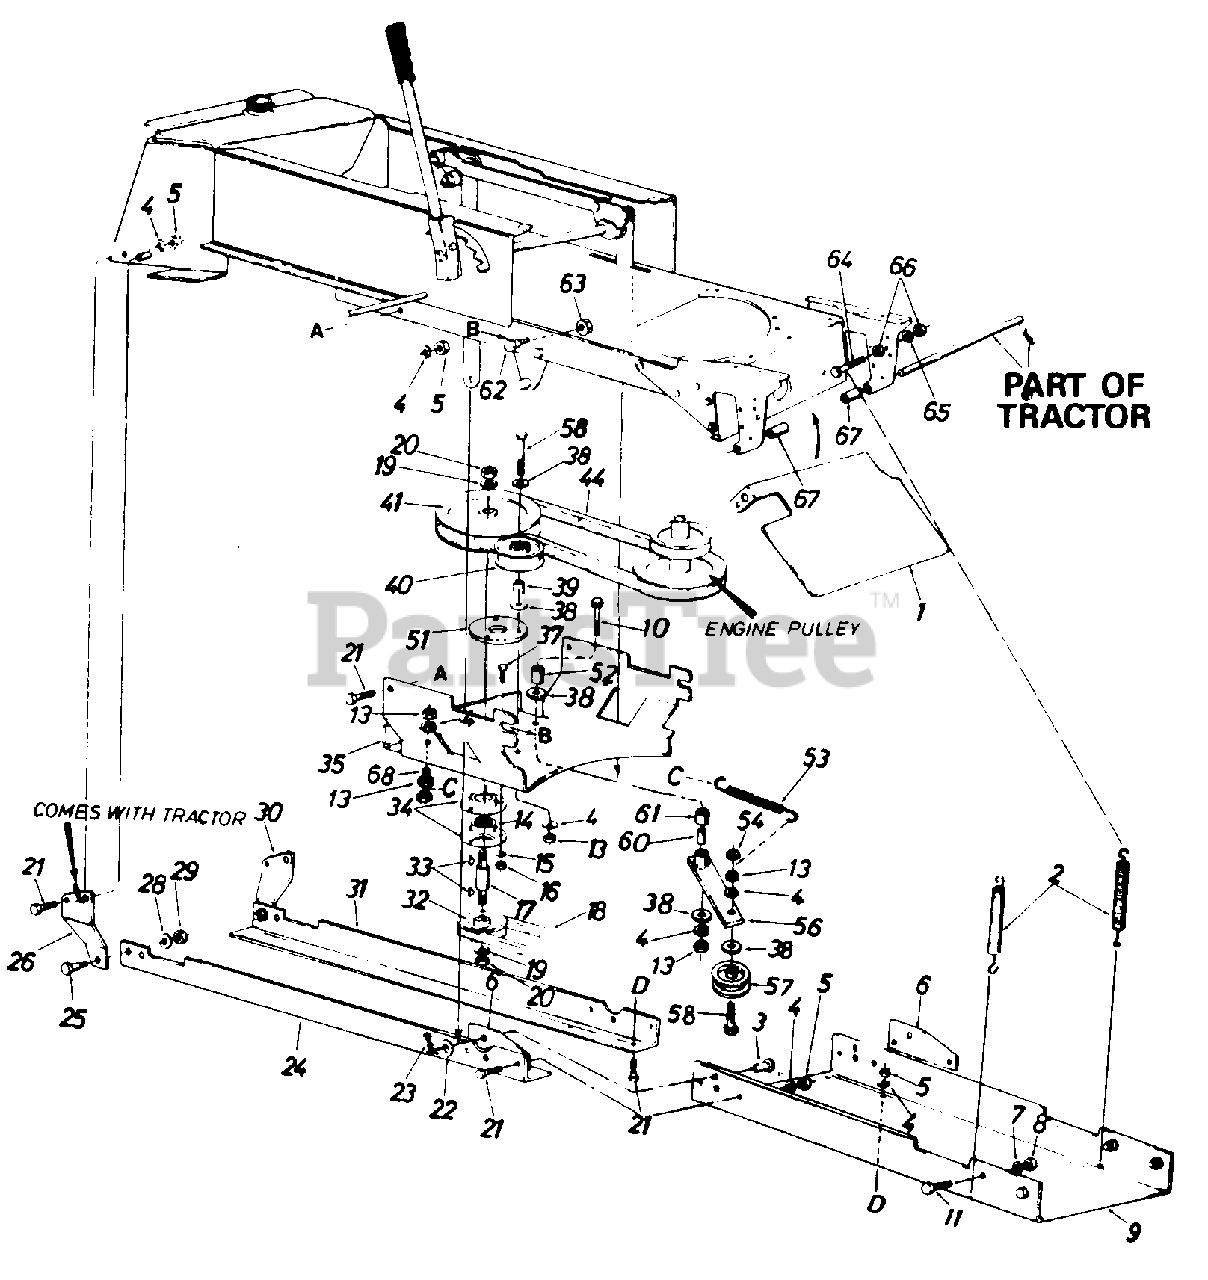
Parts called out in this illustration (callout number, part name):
3	Clevis Pin
4	L.-Wash. 3/8" I.D.
5	Hex L.-Nut 3/8-24 Thd.
6	Attaching Plate
7	L.-Wash. 1/2" I.D.
8	Hex L.-Nut 1/2-20 Thd.
11	Hex Bolt 1/2-20 x 1.25" Lg.
13	Hex Jam Nut 3/8-16 Thd.
14	Ball Beariny
15	L.-Wash. 5/16" I.D.
16	Hex Nut 5/16-18 Thd.
17	Spindle
18	"V"-Belt
19	L.-Wash. 5/8" I.D.
20	Hex Jam Nut 5/8-11 Thd.
21	Hex Bolt 3/8-24 x 1.00" Lg.
22	Flat Washer
23	Internal Cotter Pin
29	Hex Nut 7/16-14 Thd.
33	#6 Hi-Pro Key 3/16 x 5/8" Dia.
34	Bearing Housing
35	Supporting Bracket
37	Hex Sems Bolt 5/16-18 x 1"
38	Fl.-Wash. .38" I.D. x 1" O.D.
39	Spacer .38" I.D. x .62' O.D.
40	Fl.-Idler Pulley
41	Upper Drive Pulley
44	"V"-Belt
53	Extension Spring 4.75" Lg.
54	Hex Cent. L.-Nut 3/8-16 Thd.
56	Idler Arm Ass'y.
57	Idler Pulley
58	Hex Bolt 3/8-16 x 2.25" Lg.
60	Spacer.377" I.D. x .83" Lg.
61	Spacer .38" I.D. x .565" Lg.
62	Shoulder Bolt .498 Dia.
63	Hex Cent. L-Nut 3/8-16 Thd.
64	Hex Bolt 1/4-28 x 1.50" Lg.
65	L.-Wash. 1/4" I.D.
66	Hex Nut 1/4-28 Thd.
67	Spacer.63" I.D. x 1.75" Lg.
68	Hex Bolt 3/8-16 x 2" Lg.
